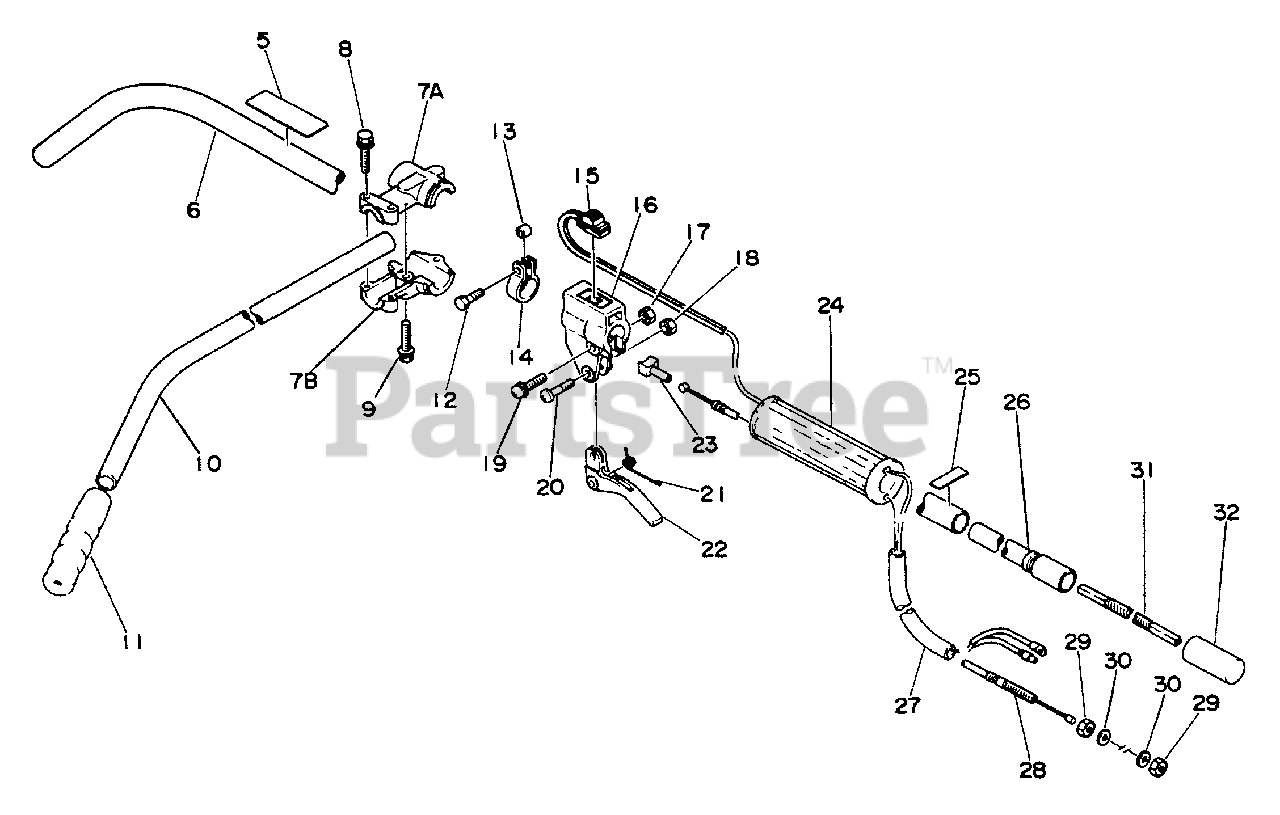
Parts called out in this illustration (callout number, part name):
5	LABEL - CAUTION
6	PIPE, MAIN
7	HANDLE BRACKET KIT
7A	HANDLE BRACKET KIT
7B	HANDLE BRACKET KIT
8	BOLT - 5×25
9	BOLT 5×28
10	HANDLE
12	BOLT 5×18
13	SPACER, GUARD
15	IGNITION SWITCH ASSY
16	BRACKET, THROTTLE
17	NUT M5
18	LOCKNUT - 5
19	SCREW 5×28
21	SPRING, THROTTLE
22	TRIGGER, THROTTLE
23	GUIDE, CABLE
24	GRIP, HANDLE
25	LABEL - ALIGNMENT
26	LINER
27	TUBE
28	CABLE, THROTTLE
30	WASHER 6.5×11.5×0.8
31	DRIVESHAFT - FLEXIBLE
32	CAP
